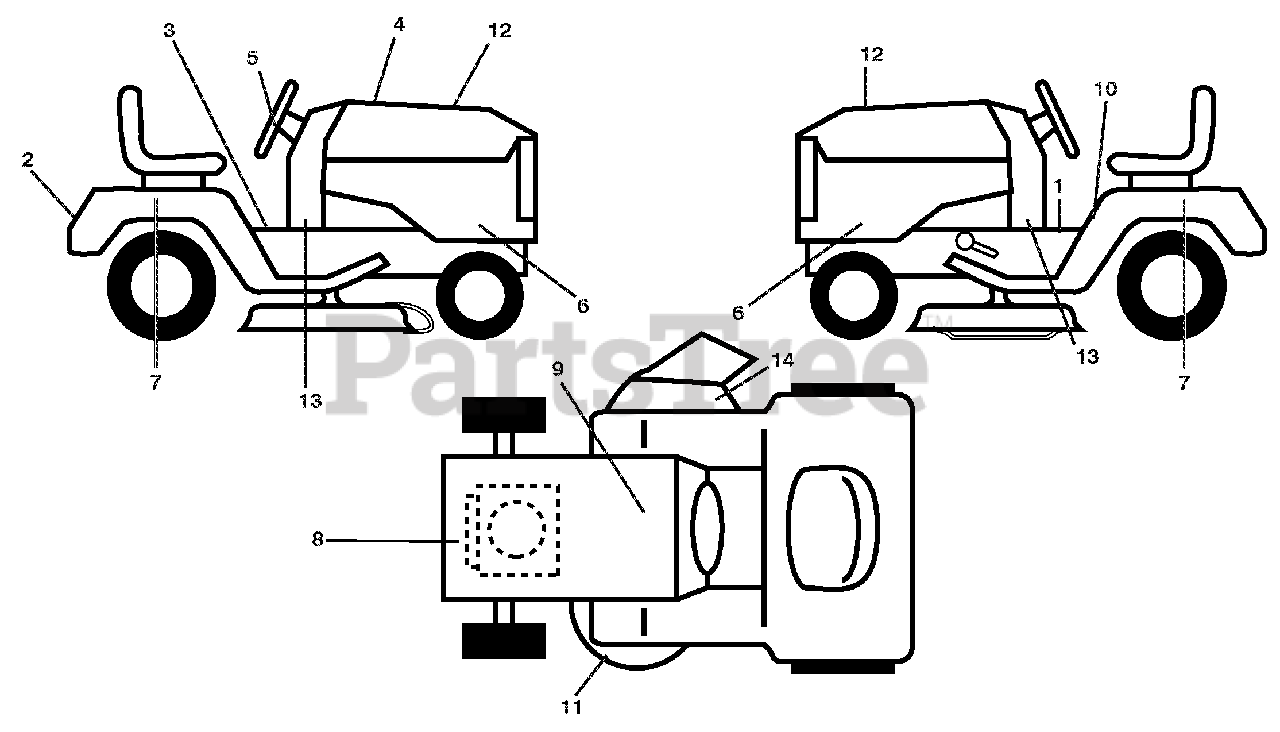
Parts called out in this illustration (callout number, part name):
1	DECAL.WARNING.START
2	DECAL.FENDER.REAR.ARIENS
3	DECAL.FENDER
4	DECAL REPLACEMENT
5	DECAL.WHEEL.STEER.ARIENS
6	DECAL.SDPNL.PWRDBY B&S.ARIENS
7	DECAL.FENDER.SIDE.HYDRO
8	DECAL.ENGINE.HP
9	DECAL.BAT.DAN/POI P/L SYM.WPN
10	DECAL.FENDER
11	DECAL.V-BELT.SCH.
12	DECAL.HOOD.LH/RH.
13	DECAL.LOWER.DASH
14	DECAL.WARNING.KEEP.HAND.AWY
